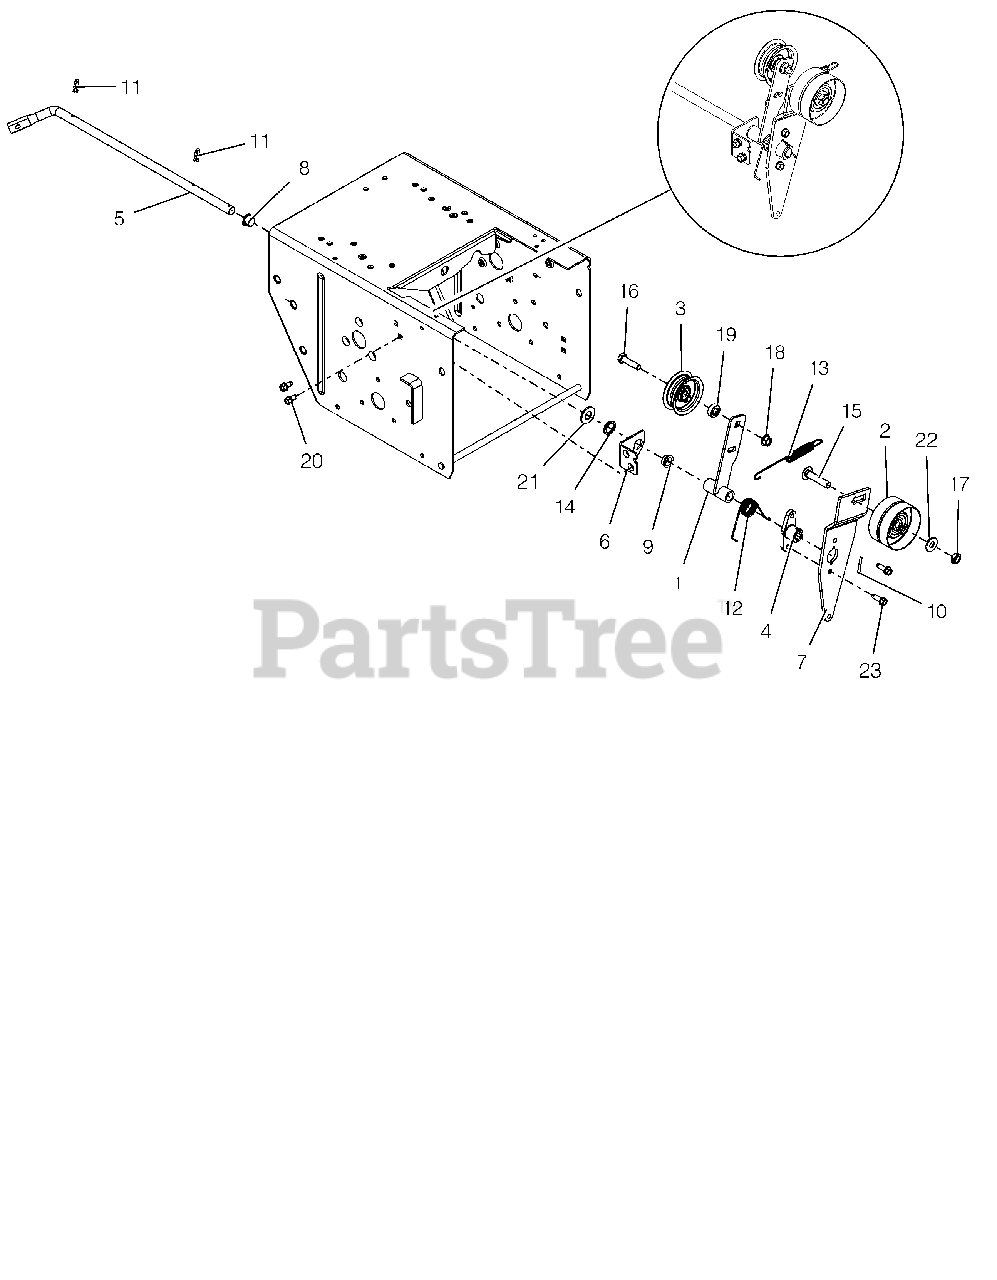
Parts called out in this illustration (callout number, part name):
1	ARM, IDLER-TRACTION
2	IDLER, FLAT-2.75 OD X .375 ID
3	IDLER, FLAT - 2.00"
4	HUB, BRAKE ARM
5	ARM, ATTACHMENT
6	BRACKET, SUPPORT
7	ARM, IDLER-ATTACHMENT
8	BUSHING, POLYLINER-.50 SPLIT
9	BSHG,FLANGE .500X.625X.270X.75
10	PIN-ROLL .125X1.00
11	CLIP, SPRING
12	SG-TORS .067X.88
13	SG-TENS .06X.482X5.35
14	WAVE SPRING .600X.875X.25FH
15	BLT-RHDSSQNK .38-16X1.75 G5YZ
16	@BLT-HEX .31-18X1.25 GR5 YWZC
17	@NUT-LK-CTR-JAM .375-16 YWZC
18	@NUT-LK-TOP-FLG .31-18 YWZC
19	SPCR, BRG .315X.500X.358X.281
20	SCR-TAP .25-20X.50 HWH TR YWZ
21	@WSHR-FL-STL.531X1.06X.095YWZC
22	@WSHR-FL-STL.38X.875X.083 YWZC
23	SCR-TAP-PM .25-20X.75 TR YWZ
